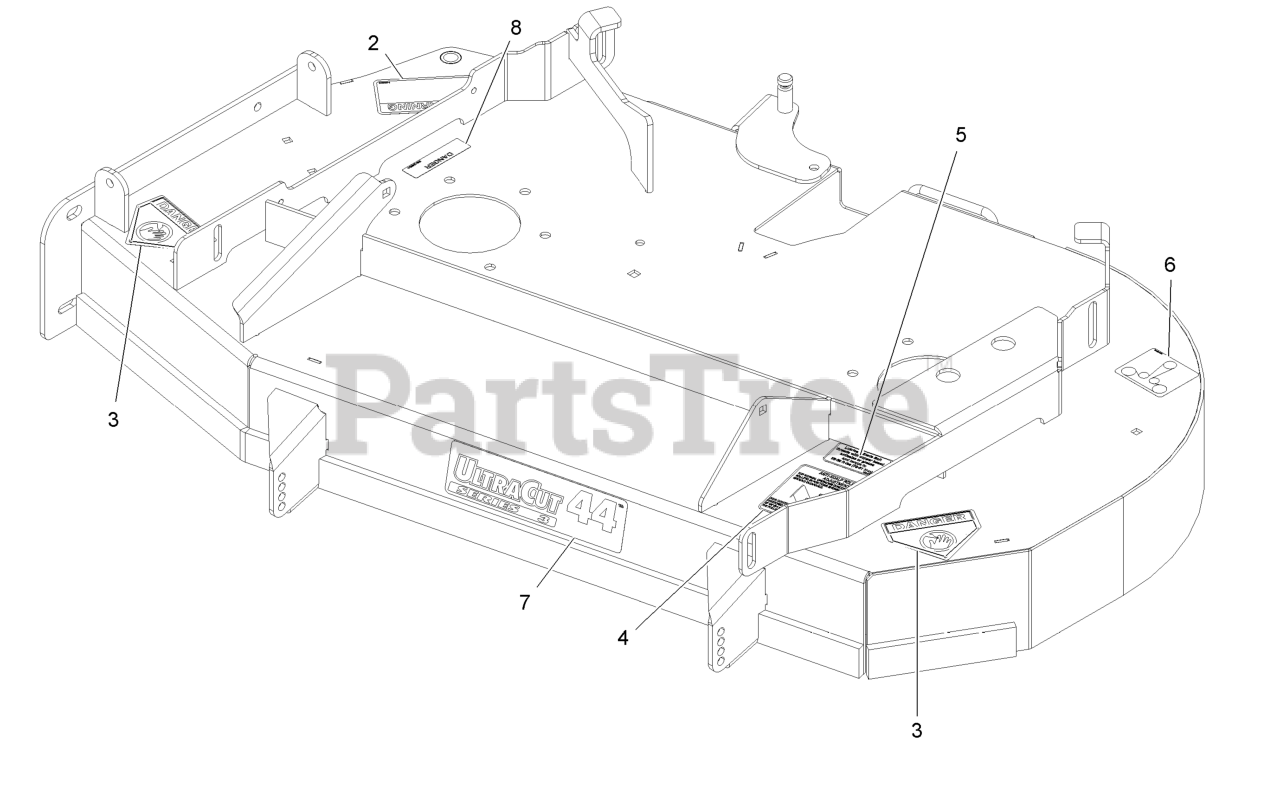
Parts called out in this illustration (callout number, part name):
2	DECAL-WARNING, DISCHARGE
3	DECAL-DANGER
4	DECAL,ANTISCALP
5	DECAL,BOLT TORQUE
6	DECAL-ROUTING, BELT
7	DECAL-ULTRACUT 44 SERIES
8	DECAL-COVER, MISSING
